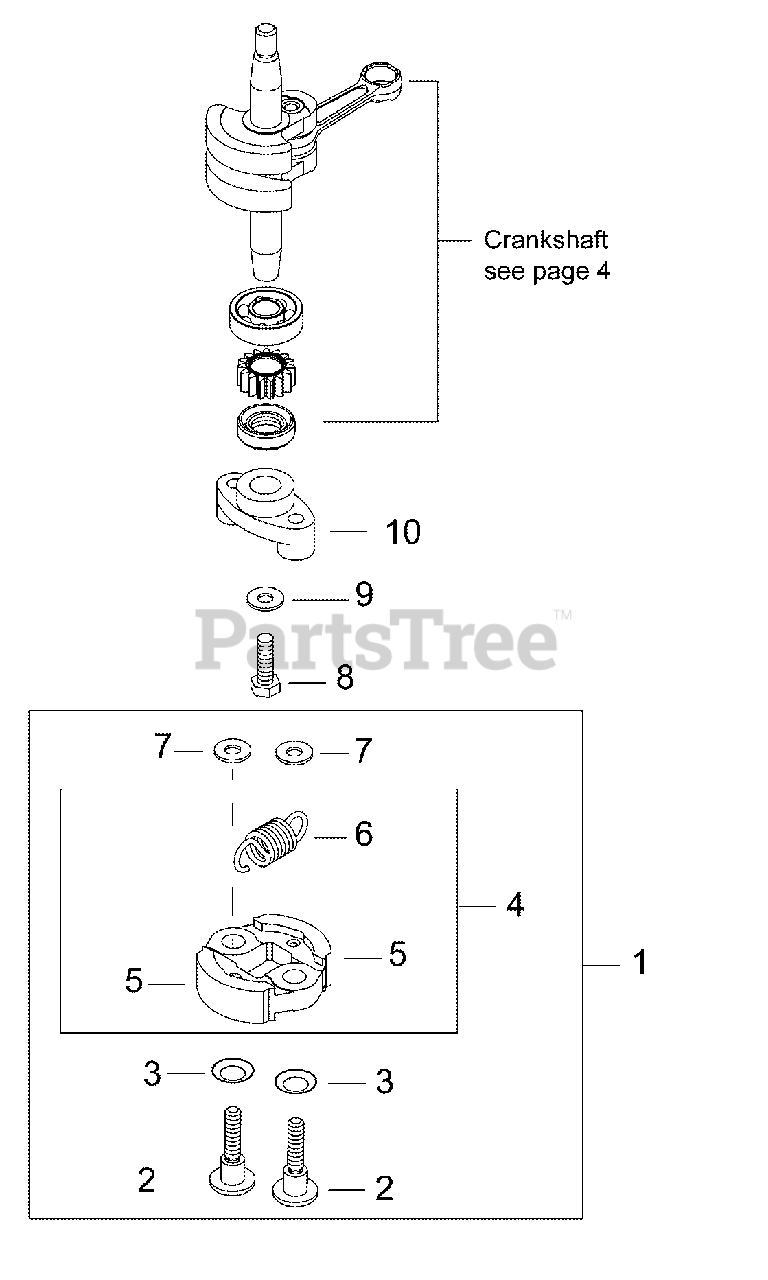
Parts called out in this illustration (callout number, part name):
1	CLUTCH KIT
2	BOLT, CLUTCH
3	WASHER - SPRING
4	CLUTCH SHOE ASSY
5	SHOE, CLUTCH
6	SPRING, CLUTCH
7	WASHER - 6
8	SCREW - 6X18
9	WASHER - 6
10	HUB, CLUTCH
